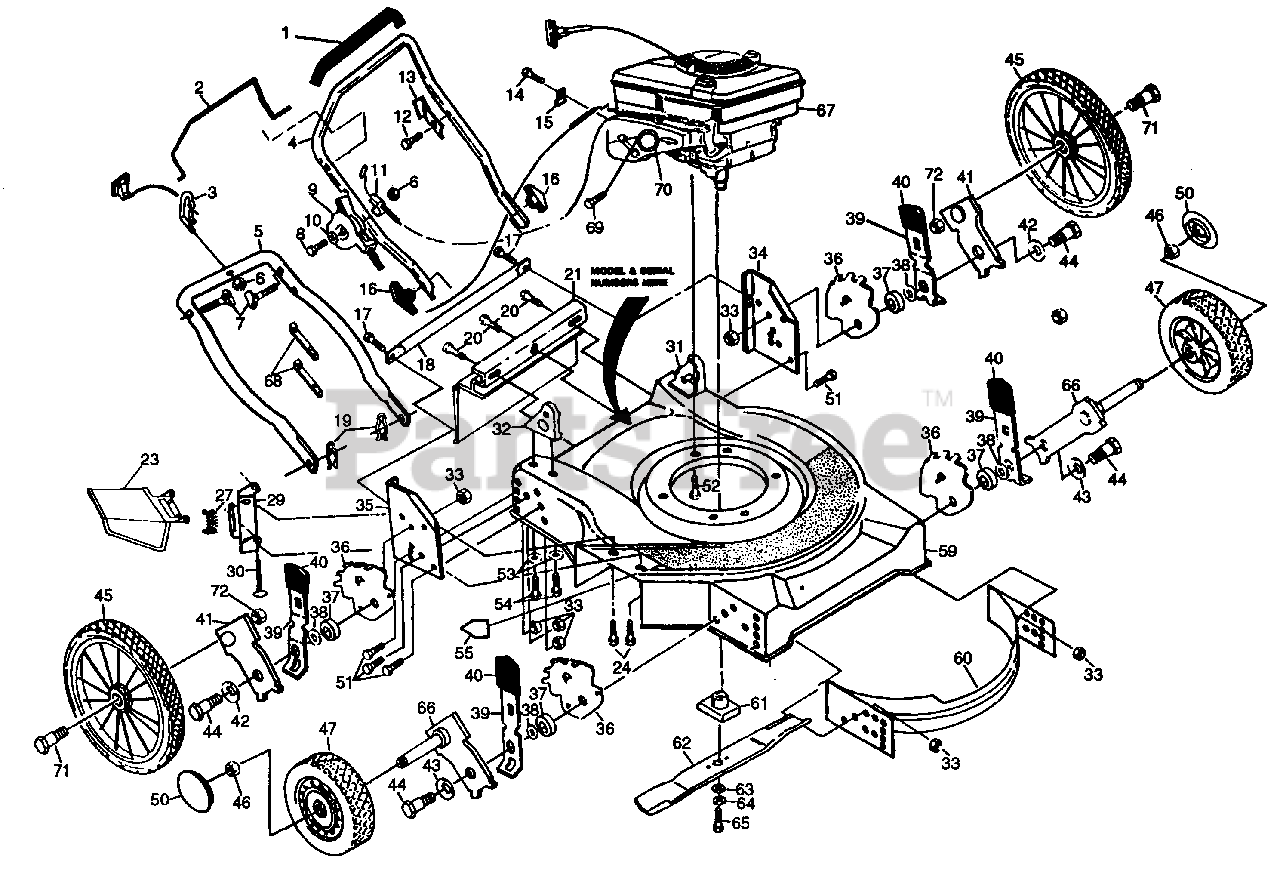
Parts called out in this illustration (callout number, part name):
1	Grip, Handle (AYP part number)
2	Bar, Control
3	Guide, Rope (AYP part number)
4	Handle, Upper (AYP part number)
5	Handle, Lower (AYP part number)
6	Locknut 1/4-20 (AYP part number)
7	Bolt, Handle 5/16-18 x 1-3/4
8	Screw, Machine 1/4-20 x 2-1/8 (AYP part number)
9	Control, Throttle
10	Washer, Flat (AYP part number)
11	Engine, Zone Control Cable (AYP part number)
12	Screw, Hex Washer Head 10-24 x 1/2 (AYP part number)
13	Bracket, Up-Stop (AYP part number)
14	Screw, Thread Rolling 10-32 x 5/8 (AYP part number)
15	Clamp, Cable (AYP part number)
16	Knob, Handle (AYP part number)
17	Screw, Hex, Tapping 1/4-20 x 1/2 (AYP part number)
18	Rod, Support (AYP part number)
19	Cotter, Hairpin (AYP part number)
20	Screw, Hex, Washer Head, Tapping 10-24 x 1/2 (AYP part number)
21	Skirt, Rear (AYP part number)
23	Guard, Discharge
24	Screw, Hex Head Thread Rolling 1/4-20 x 3/4 (AYP part number)
27	Spring, Torsion (AYP part number)
29	Bracket, Housing (AYP part number)
30	Rod, Hinge (AYP part number)
31	Bracket Assembly, Handle (Left) (AYP part number)
32	Bracket Assembly, Handle (Right) (AYP part number)
33	Locknut 3/8-16 (AYP part number)
34	Bracket, Wheel, Support (Left) (AYP part number)
35	Bracket, Wheel, Support (Right) (AYP part number)
36	Bracket, Wheel, Adjusting (L.R. & R.F.) (AYP part number)
37	Spacer (AYP part number)
38	Washer, Flat (AYP part number)
39	Spring, Selector (AYP part number)
40	Knob, Selector (AYP part number)
41	Arm Assembly, Axle (Rear) (AYP part number)
42	Washer, Spring, Rear (AYP part number)
43	Washer, Belleville (AYP part number)
44	Bolt, Shoulder 3/8-16 (AYP part number)
45	Assembly, Wheel and Tire (AYP part number)
46	Locknut 3/8-16 (AYP part number)
47	Assembly, Wheel and Tire
50	Cap, Hub (AYP part number)
51	Bolt, Hex Head 3/8-16 x 3/4 (AYP part number)
52	Screw, Hex Head Thread Rolling (AYP part number)
53	Washer, Flat (AYP part number)
54	Screw, Thread, Cutting 5/16-18 x 3/4 (AYP part number)
55	Decal, Danger (AYP part number)
59	Housing, Lawn Mower
60	Baffle, Front (AYP part number)
61	Adapter, Blade (AYP part number)
62	Blade, 22"
63	Washer, Hardened (AYP part number)
64	Washer, Lock, Helical 3/8 (AYP part number)
65	Screw, Hex, Head 3/8-24 x 1-3/8
66	Arm Assembly, Axle (Front) (AYP part number)
68	Tie, Wire (AYP part number)
69	Screw 8-32 x 3/8 (AYP part number)
70	Deflector, Muffler
71	Bolt, Shoulder (AYP part number)
72	Nut, Lock 3/8-16 (AYP part number)
